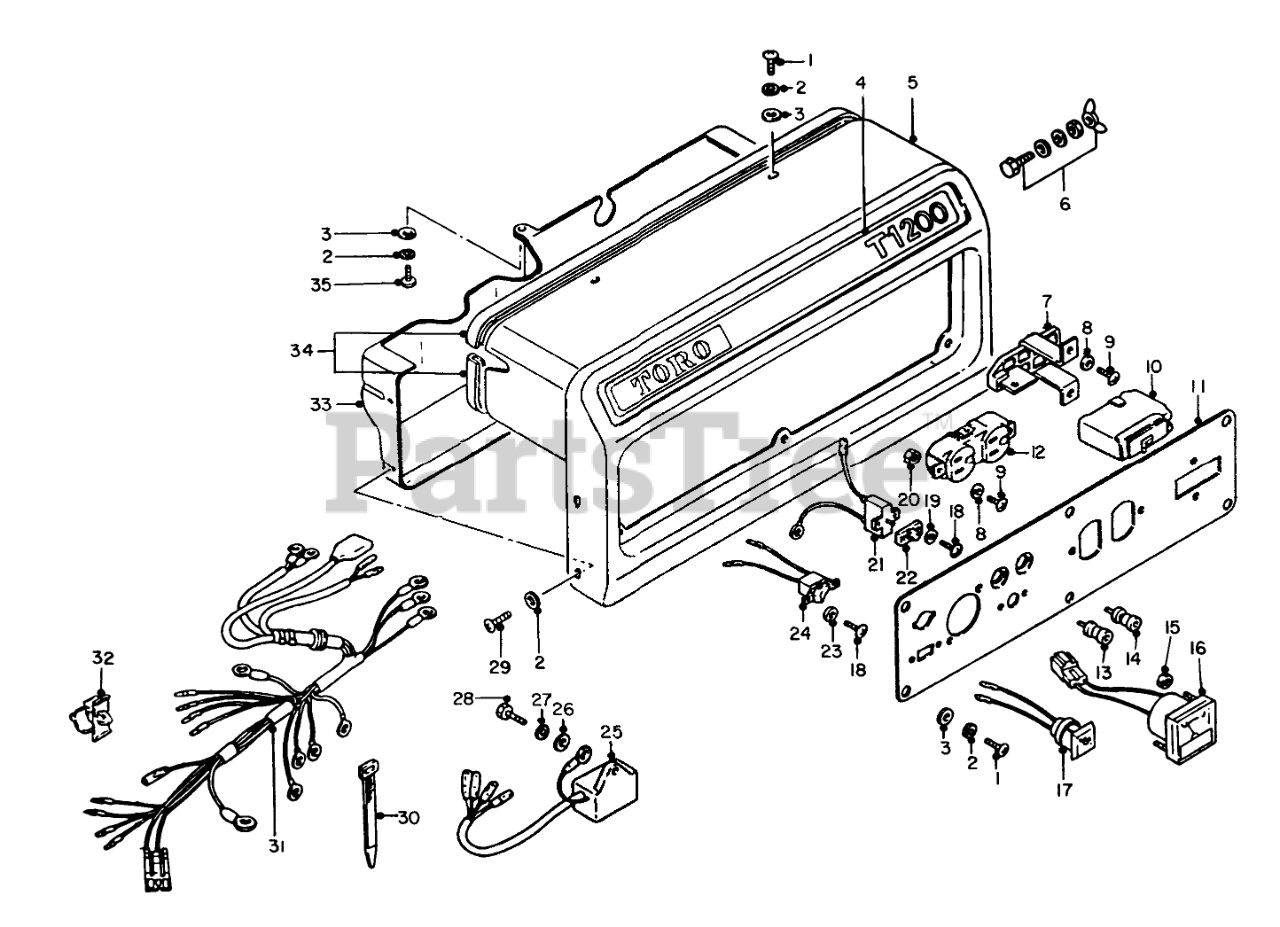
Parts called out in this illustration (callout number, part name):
1	SCREW
2	Washer
3	WASHER
4	Emblem-Toro
5	Panel-Control
6	GROUND TERMINAL
7	BREAKER HOLDER
8	Washer
9	Screw
10	Circuit Breaker
11	PLATE
12	RECEPTACLE
13	TERMINAL-
16	Meter-Voltage
18	Screw
19	Washer-Lock
21	Protector-Circuit
23	Washer
24	Switch
25	OIL LEVEL UNIT
26	Washer
27	LOCKWASHER
29	Screw
30	Clamp
31	CONTROL HARNESS
32	Clamp
33	Panel-Rear
35	Screw
